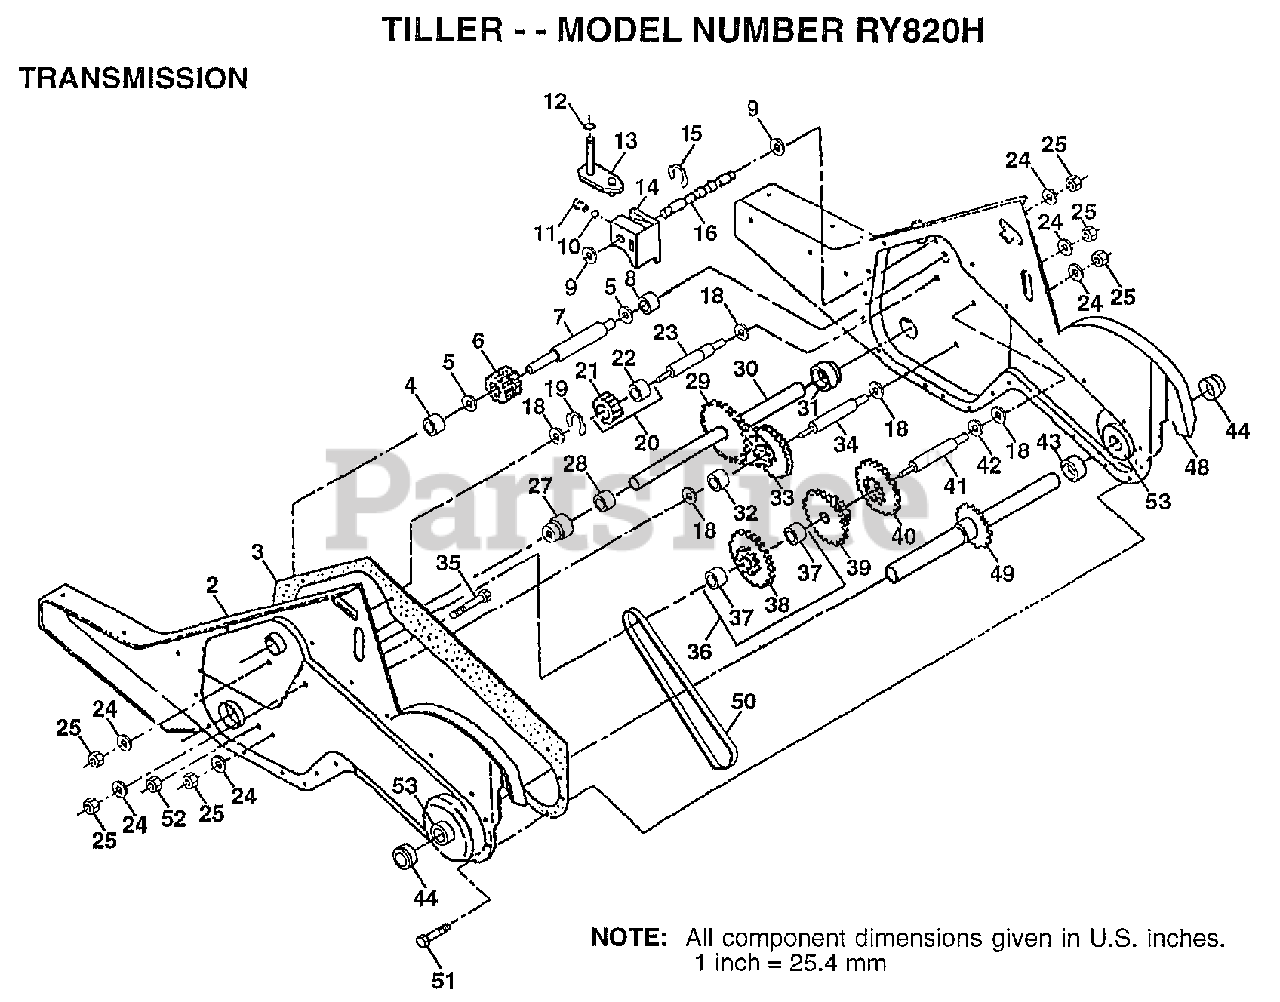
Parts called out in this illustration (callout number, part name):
2	GEARCASE LH W/BRG
3	GASKET TI
4	NEEDLE BRNG LT
5	"T, BEARING"
6	GEAR PINION INPUT
7	"SHAFT.INPUT.""D"""
8	"TI, BEARING"
9	WASHER SEAL
11	SPRING-SHIFT CRT
12	O-RING TI
13	BRACKET ASM SHIFT
14	SHIFT FORK TI
15	KLIP RING
16	SHAFT.SHIFTER
18	WASHER
19	KLIP RING
20	GEAR ASSY CRT
21	GEAR-REV IDLR CRT
22	NEEDLE BEARING TI
23	SHAFT CRT
24	LOCKWASHER
25	NUT.ASF.HEX.7/16
27	BEARING.SHAFT.LH.
28	BUSHING TI
29	CHAIN CRT
30	GROUND SHAFT ASSY
31	BEARING.SHAFT.RH.
32	SPACER TI
33	SPRCKT 8 GEAR CRT
34	SHFT 2ND RED. CRT
35	SCRW WHIZ LOK CRT
36	SPROCKET.ASM.W/BR
37	BEARING
39	GEAR TI
40	GEAR TI
41	REDUCTION SHFT TI
42	BRNG RACE
43	SPACER TI
44	SEAL ASM-OIL
48	GEARCASE RH W/BRG
49	TINE SHAFT
50	CHAIN.50 LINK TI
51	SCREW
52	NUT.HEX.5/16-18
